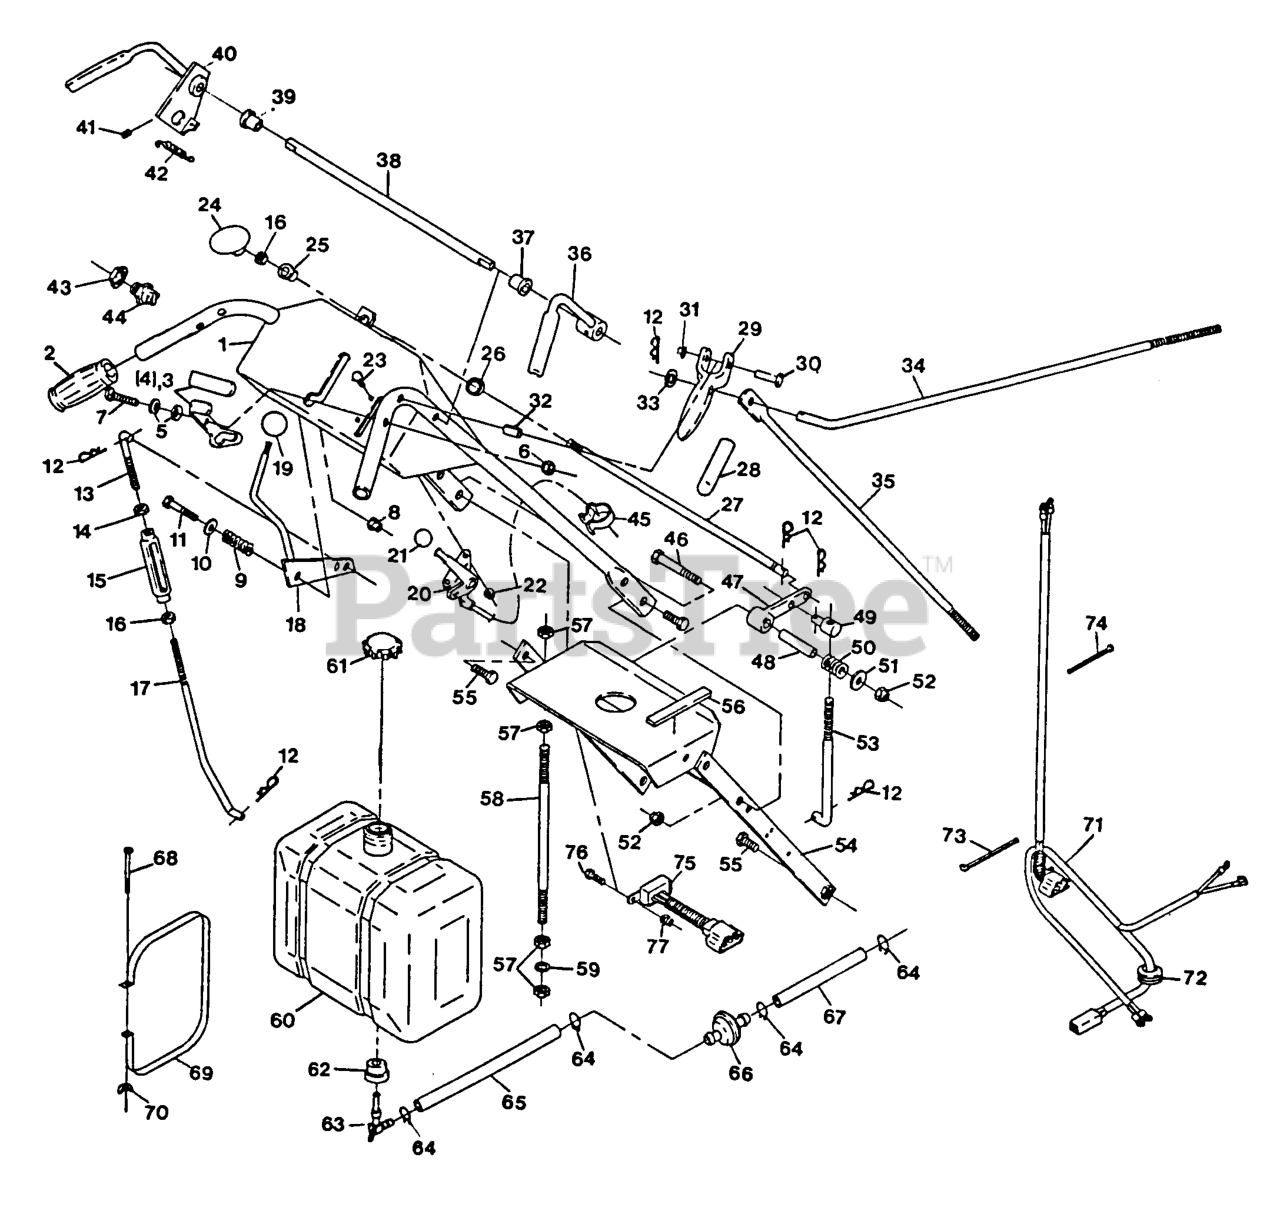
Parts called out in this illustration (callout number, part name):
3	LATCH,W/GRIP RH
4	LATCH,W/GRIP LH
5	WASHER-SPRING
12	PIN-COTTER
13	ROD,PTO RH LOW LH THD
17	ROD,PTO LOW RH THD
19	KNOB-BALL
20	CABLE,THROTTLE CONTROL
21	KNOB-BALL
23	BOLT-CARR
24	KNOB-PUSH / PULL
25	BEARING-NYLON
26	NUT-PUSH
28	GRIP-LEVER, DRIVE
29	DRIVE LEVER ASM
30	PIN-LEVER, DRIVE
31	NUT-PUSH
32	PIN-ROLL
34	LINKAGE,BRAKE
35	LINKAGE,CALIPER
37	BUSHING-NYLON
38	ROD,CONNECTING
39	BUSHING,FLANGED
41	SCREW-SET
42	SPRING-EXTENSION
44	SWITCH,OPERATOR CNTRL
45	CLIP-CABLE
49	SWIVEL,SHORT ADJUSTING
50	SPRING-COMPRESSION
56	PAD,PLASTIC TANK
61	CAP-FUEL
68	SCRW,MACH CRPH
70	WINGNUT
72	GROMMET
73	TIE-PLASTIC
74	TIE-CABLE
